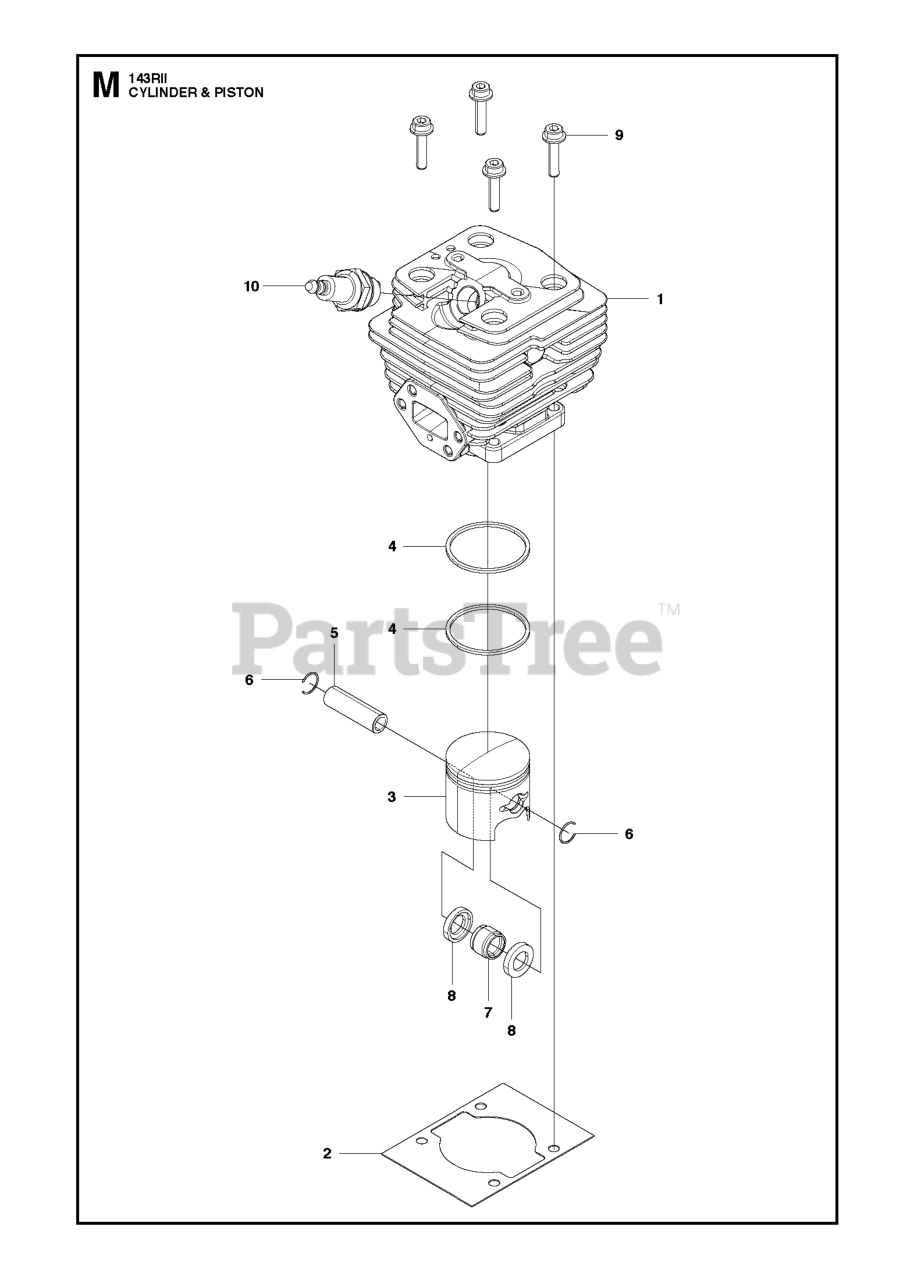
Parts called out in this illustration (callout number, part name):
4	RING, PISTON 2/PK
5	PISTON PIN
7	ROLLER BEARING
